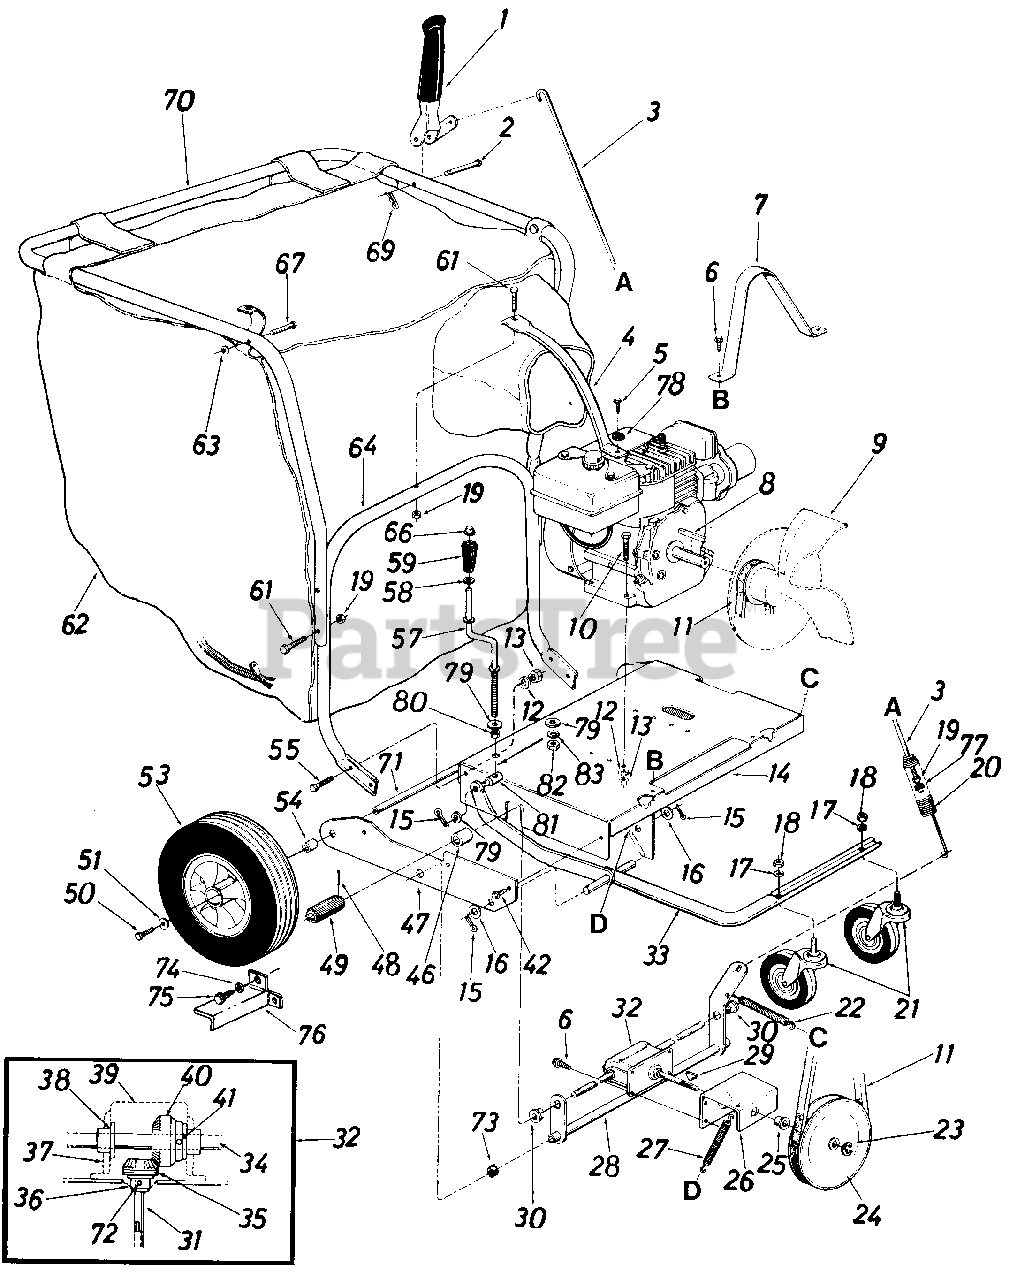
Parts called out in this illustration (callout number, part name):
1	Clutch Grip Ass'y.
2	Clevis Pin .375" Dia. x 1.88"
3	Clutch Rod 32" Lg.
4	Handle Brace
5	Part of Engine
6	Hex L-Wash. Hd. AB Tap Scr. 1/4" x .62" Lg.
9	Air Vane Plate Ass'y.
10	Hex Bolt 5/16-18 x 1.5" Lg.*
11	"V"-Belt 1/2" x 26" Lg.
12	L.-Wash. 5/16" I.D.
13	Hex Nut 5/16-18 Thd.*
16	Fl.-Wash. .63" I.D. x 1.25" O.D.
17	L.-Wash. 1/2" I.D.*
18	Hex Nut 1/2-13 Thd.*
19	Hex Cent. L.-Nut 1/4-20 Thd.
20	Extension Spring .78" O.D. x .75" Lg.
21	Swivel Caster Wheel 5" Dia. x 1.25"
22	Extension Spring .38" O.D. x 7.50" Lg.
23	Snap "E"-Ring.50" Dia. Shaft
24	"V"-Pulley 5/8" x 6.50" O.D.
25	Flange Bearing .502" I.D.
28	Clutch Bracket Ass'y.
29	#2 Woodruff Key 3/32" Dia. x .81" Lg.
30	Hex Flange Bearing Bronze .625 " I.D.
31	Pinion Shaft .50" Dia. x 5.0"
32	Gear Box Ass'y. Comp.
35	Bevel Gear .50" I.D. x 14 Teeth
36	Flange Bearing .503" I.D.
37	Gear Box
38	Flange Bearing .630" I.D.
39	Gear Box Cover
40	Bevel Gear .62" I.D. x 28 Teeth
41	Spring Pin Spiral 3/16" Dia. x 1.25" Lg.
42	Hex Wash. Hd. "AB" Tap Scr. 5/16" x .75" Lg.
46	Spacer .63 I.D. x .88" O.D. x .56" Lg.
49	Drive Pinion
50	Hex Locking Bolt 5/16-24 x.62" Lg.
51	Fl.-Wash. .34" I.D. x 87" O.D.
53	Wheel Ass'y. - Comp. 12" x 3" (Incl. Ball Bearings)
54	Spacer .63" I.D. x 1.00" O.D. x.94" Lg.
55	Hex Bolt 5/16-18x .75" Lg.*
57	Height Adjustment Crank
58	Fl.-Wash. 138" I.D. x .62" O.D.
59	Crank Knob
61	Hex Bolt 1/4-20 x 1.75" Lg.
62	Vacuum Bag- Felt
63	Push Speed Nut .25" Dia. Stud
64	Lower Handle
66	Push Nut 3/8" Dia.
67	Stud Pin .250" Dia. x 1.75"
69	Internal Cotter Pin 3/8" Dia.
70	Upper Handle
71	Rear Axle .624" Dia. x 24.37"
72	Spring Roll Pin 5/32" Dia. x 1.12
73	Spacer .82" I.D. x 1.00" O.D. x .305 Lg.
74	L.-Wash. .265" I.D.
75	Hex Self Tap Scr. 1/4" x 3/8" Lg.
78	Belleville Washer
79	Fl.-Wash. .35 " I.D. x .87" O.D.
80	Spacer .38" I.D. x .50" O.D. x .180" Lg.
81	Ferrule 3/8-16 x .38" Dia.
82	Hex Nut 3/8-16 Thd.*
83	L.-Wash. 3/8" I.D.*
